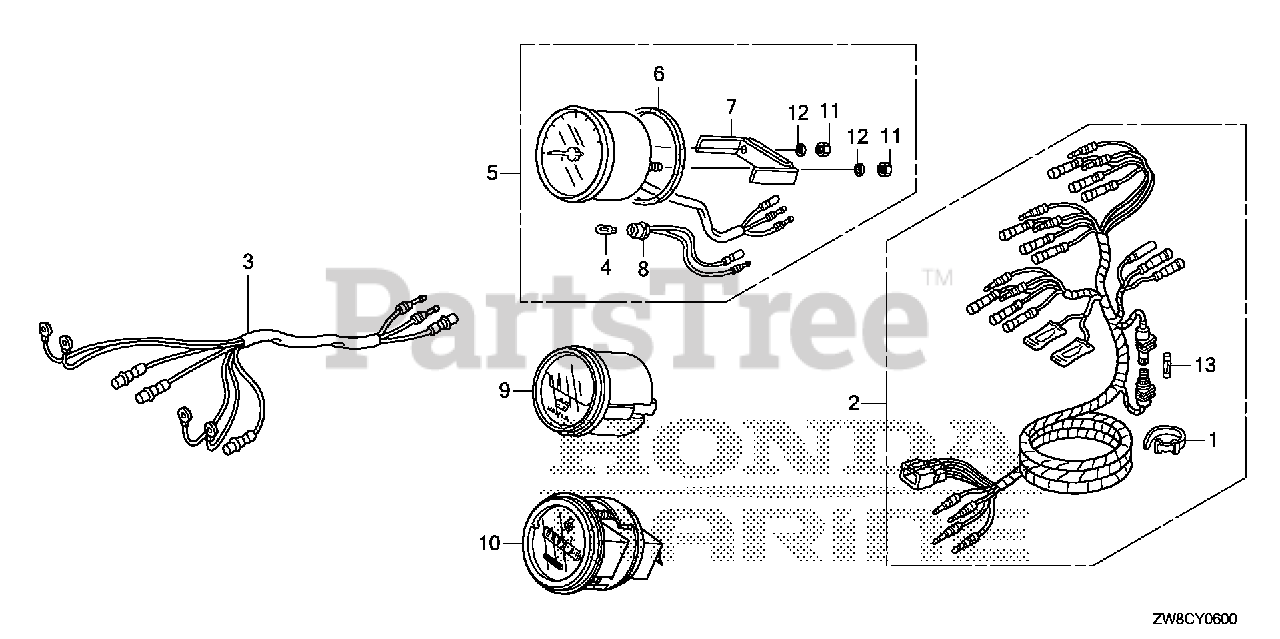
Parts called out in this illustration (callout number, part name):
1	BAND B1, WIRE
2	HARNESS ASSY., METER (A)
3	HARNESS ASSY., METER (B)
4	BULB, WEDGE BASE (T10) (12V 1.7W) (STANLEY)
5	TACHOMETER ASSY.
9	METER ASSY., VOLT
10	METER ASSY., HOUR L.C.D.
11	NUT, HEX. (5MM)
12	WASHER, SPRING (5MM)
13	FUSE A (10A)
